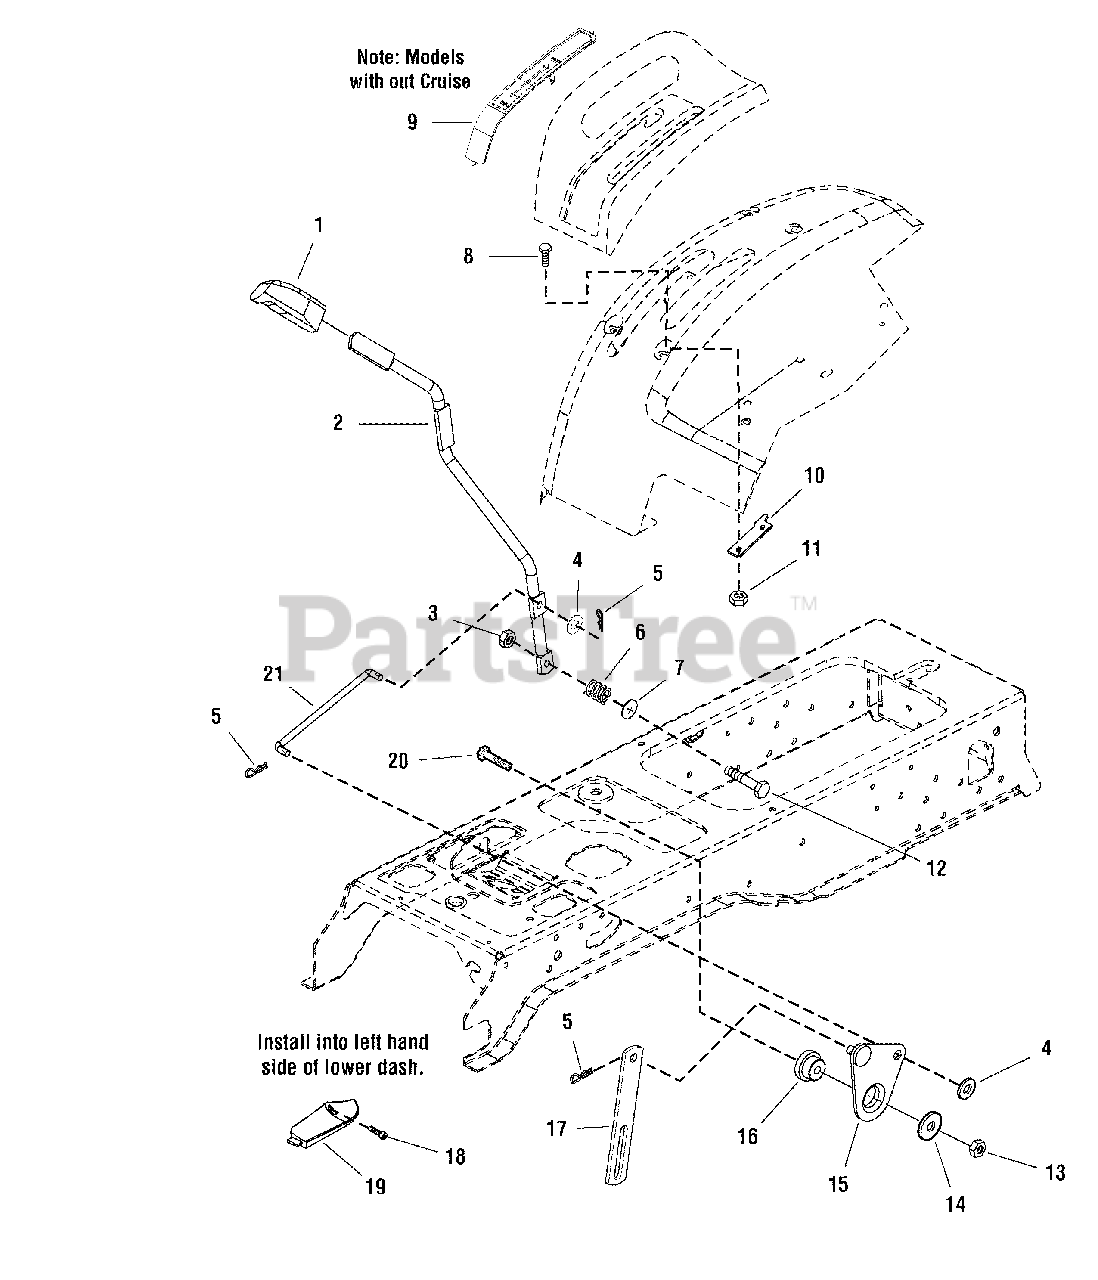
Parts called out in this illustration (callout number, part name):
1	GRIP, Black Vinyl
2	ROD, Lift Lever with Flats
3	NUT, Hex Flange Lock, 3/8-16
4	WASHER
5	PIN, Quick
6	SPRING, Compression
7	NUT, Push, 3/8
8	CAPSCREW, Hex Head, 1/4-20 x 3/4
9	PLUG, Lift Cover (Models without Cruise Control)
10	QUADRANT
11	NUT, Hex Lock ESNA, 1/4-20
12	CAPSCREW, Hex Head, 3/8-16 x 2
13	NUT, ESNA Lock, 5/16-18
14	WASHER, Flat, 5/16 x 1-1/4
15	CAM ASSEMBLY, Lift
16	SPACER
17	LINK, Lift Upper
18	SCREW, Torx Head, # 8-16 x 1/2
19	COVER, Dash
20	CAPSCREW, Hex Head, 5/16-18 x 1-1/4
21	ROD, Lift
